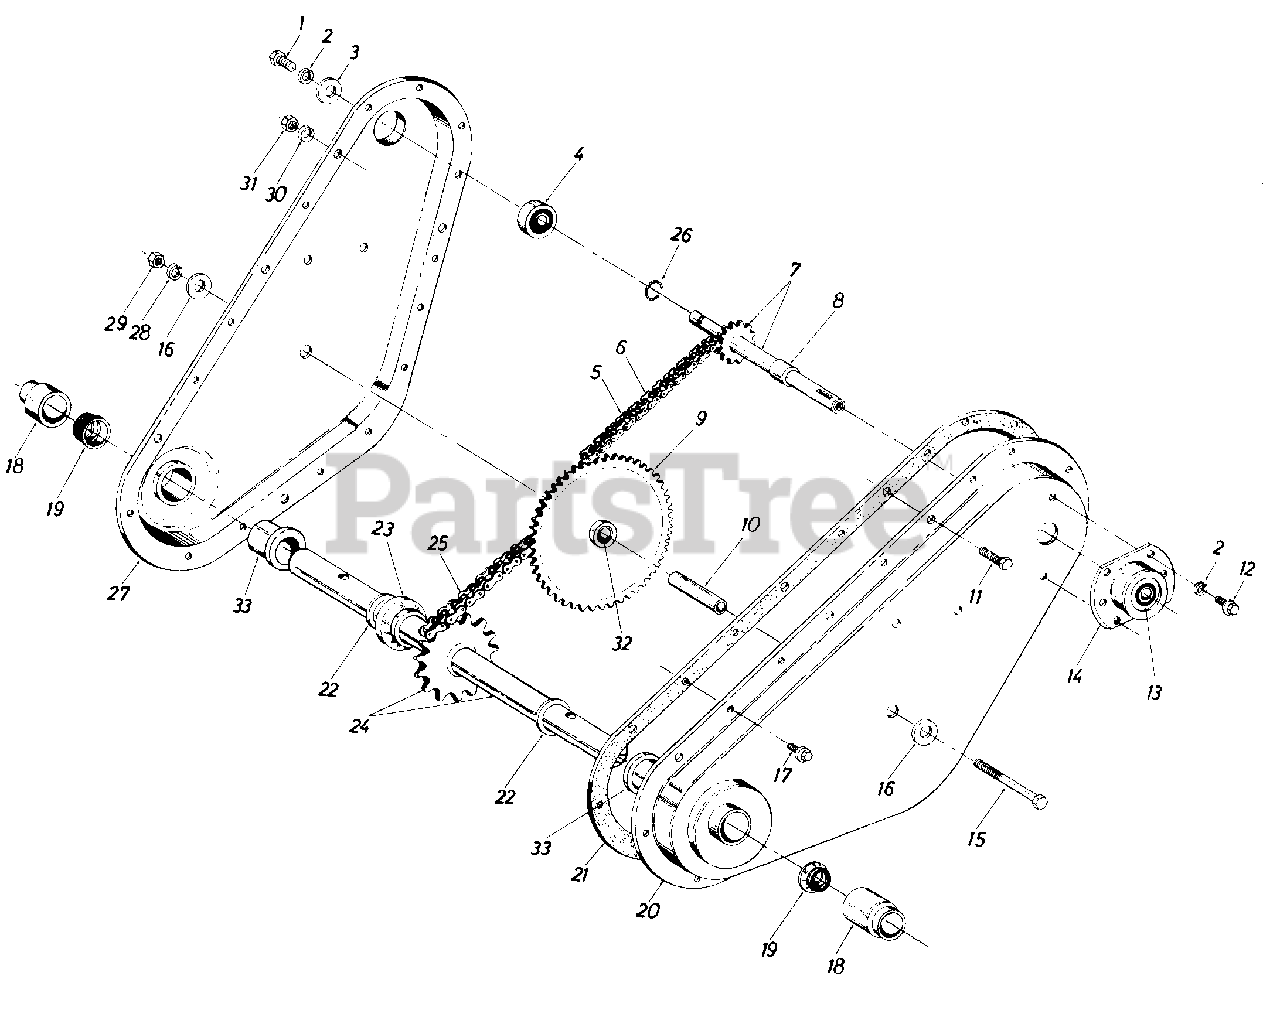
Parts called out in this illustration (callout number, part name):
1	Hex L-Bolt 1/4-28 x .625 Lg.
2	L-Wash. 1/4 I.D.
3	Fl-Wash. .25 I.D. x .93 O.D. x .125" Thk.
4	Bearing .62 I.D. x 1.38 O.D. x .437" Thk.
5	#35 Chain 3/8 Pitch x 52 Links Endless
6	Master Link
7	Input Shaft Assembly
8	Spacer
9	Sprocket Assembly
10	Sprocket Hub Tubing 3/8" I.D. x 5/8" O.D. x 1.9" Lg.
11	Hex Bolt 5/16-18 x .625" Lg.
12	Hex Wash. Hd. Self-Tap Scr. 1/4-20 X .Son Lg.
13	Bearing .625" I.D. x 1.38" O.D. x .437 Thk.
14	Bearing Housing
15	Hex Bolt 3/8-24 X 2.75" Lg.
16	Fl-Wash. 3/8" I.D. x 1.25" O.D. x .l00" Thk.
17	Hex Wash. Hd. Self-Tap Scr. 1/4-20 x 50" Lg.
18	Dust Cap
22	Thrust Wash. 1.00" I.D. x 030" Thk.
23	Step Spacer
24	Tine Shaft Assembly
25	#50 Chain 5/8" Pitch x 46 Links Endless
26	Snap Ring 5/8" Dia. Shaft
29	Hex Nut 3/8-24 Thd.
30	L-Wash. 5/16" I.D.
31	Hex Nut 5/16-18 Thd.
32	Bearing
33	Bearing
